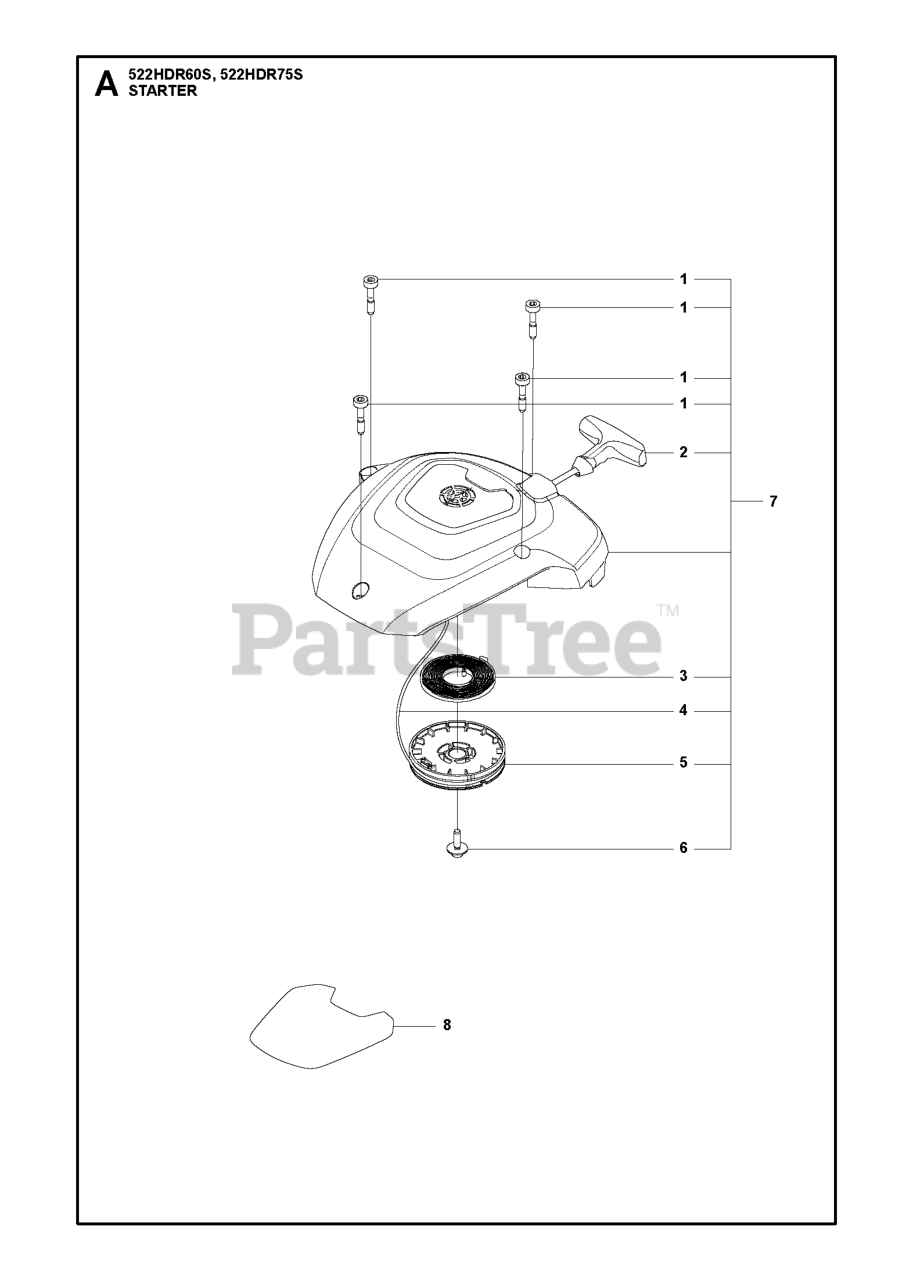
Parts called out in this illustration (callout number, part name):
1	SCREW CITXSCMO M5X25
2	STARTER HANDLE
4	STARTER CORD
5	STARTER PULLEY
6	SCREW ITXSCT PL5X16 10.9 TBO
7	STARTER ASSY 522
8	LABEL STARTER 522HDR60S
8	LABEL STARTER 522HDR75S
